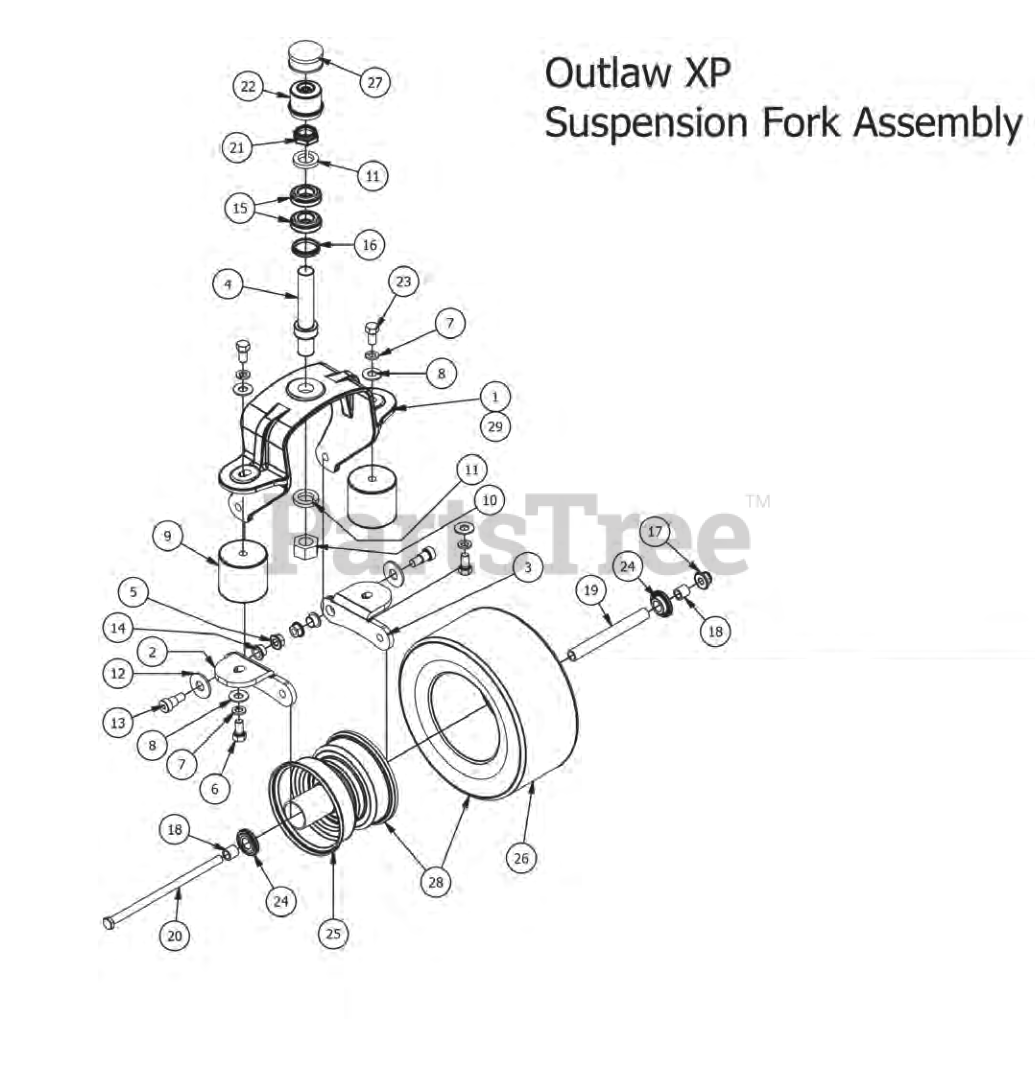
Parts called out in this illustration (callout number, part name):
1	Suspension Fork Top/Side Combo
2	Suspension Fork-Bottom Left
3	Suspension Fork - Bottom Right
4	Front Suspension Fork Spindle
5	1/2" Flange Nut
6	1/2" x 1" Hex Bolt
7	1/2" Lock Washer
8	1/2" Washer (Grade 8)
9	Vibration Mount- Red Dot
10	1" Fine Thread Nut
11	1" Lock Washer
12	5/8" Flat Washer
13	5/8" x 5/8" Shoulder Bolt
14	Bronze Bushing - SF-2024-8
17	1/2-13 Nylon Flange Nut-Orange
18	3/4 OD x 1/2 ID x 3\4 Length
19	Front Wheel Spanner
20	1/2" x 10" Bolt
21	1" Fine Thread 1/2 Nut
22	Dust Cover
23	1/2" x 1-1/4" Gr5 Hex Bolt (Coarse)
24	1-3/4" Bearing-Large Bore Front Rim
25	Black Front Tire Rim
26	13 x 6.50-6 Tire:
27	Spring Cap Cover
28	13x6.5-6 Large Bore- Black Front Assembly
29	Suspension Fork Assembly
